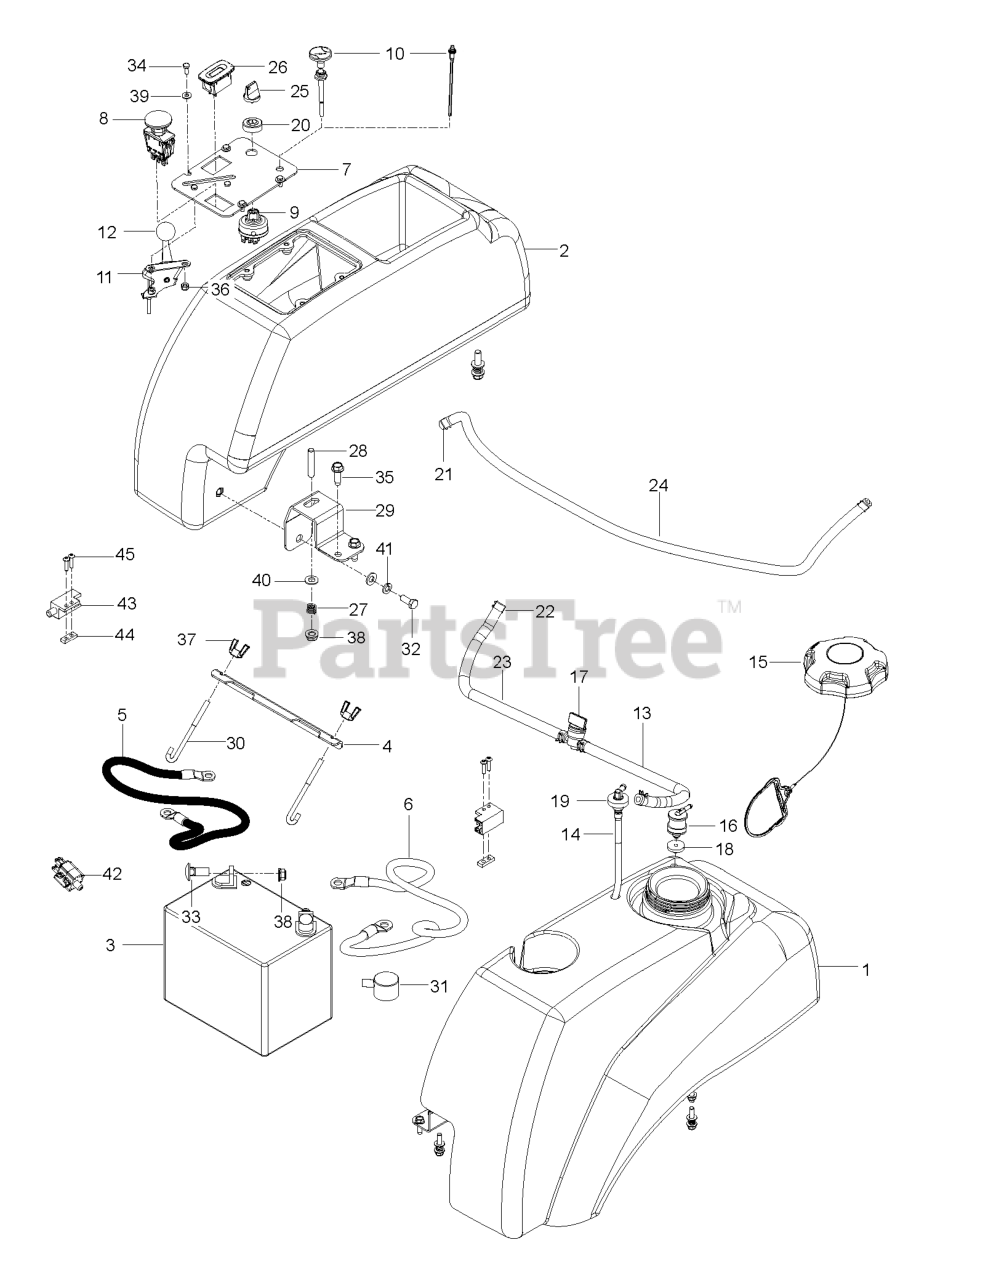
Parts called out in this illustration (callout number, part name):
1	FUEL.TANK.ASSY.LH.MZ.GRY.17
2	FENDER CONSOLE
3	BATTERY, 12 V 330 AMP
4	BRACKET.BATTERY.MOUNT.PLATED
4	Brackets
4	BRACKET, BATTERY MOUNT
5	CABLE.GROUND.BATT.MZ.BLACK.39"
6	CABLE.BATT.SOLENOID.MZ.RED.25"
7	PLATE.PNT.CONSOLE.MZ.EDIP
7	PLATE.CONSOLE.BLACK
8	RP SWITCH.PTO.TERMINAL.STD.RED
8	SWITCH, PTO 10 AMP
9	SWITCH, IGNITION, INDAK
10	CHOKE CONTROL CABLE 57"
10	CABLE, CHOKE, 38
10	LED.LIGHT.SERVICE.EFI
11	THROTTLE CONTROL W/BALL KNOB
11	THROTTLE CABLE
12	KNOB.ROUND.BALL.BLACK
13	FUEL.HOSE.SHUT.OFF.ASM.10".10"
13	FUEL.HOSE.SHUT.OFF.ASM.10".26"
14	FITTING, FUEL
15	CAP, FUEL
16	VALVE.FUEL.CHECK
17	FUEL VALVE
18	GROMMET, CHECK VALVE
19	RUBBER GROMMET
20	CAP IGNITION NUT
21	CLAMP, HOSE
22	HOSE CLAMP
23	HOSE.1/4".LOW.PERM.FUEL.LN.10"
24	HOSE.3/16".VAPOR.LINE.39"LGTH
24	HOSE.3/16".VAPOR.LINE.55"LGTH
24	HOSE.3/16".VAPOR.LINE.64"LGTH
24	HOSE.3/16".VAPOR.LINE.36"LGTH
25	KEY, IGNITION
26	GUAGE.SRVCMNDR.HRMTR.
28	STUD, 5/16C
29	SUPPORT.PNT.TANK.FRONT.STAMPED
29	SUPPORT, TANK, BLK
31	COVER.TERMINAL.BATTERY
32	BOLT.FIN.HEX.5/16-18X3/4
32	HCS 5/16C X 3/4
33	RP BOLT 5/16-18 X3/4 ZN/YEL GR
33	BOLT 5/16C X 3/4" CARRIAGE
34	HCS #10-24 X 1/2
34	SCREW
35	SCREW
35	HCS #10-24 X 1/2
36	NUT 10-24 NYLOC
37	WING NUT 1/4
38	5/16-18 NYLOC FLANGE NUT
40	WASHER
41	WASHER.LOCK.HVY.HLCL.SPR.5/16
42	SWITCH.INTRLCK.CLUTCH.
42	SWITCH, BRAKE 3P
43	SWITCH INTERLOCKT
44	PLATE NUT ZTR
45	SCR #10-24 X .75 SKT HD BLK
